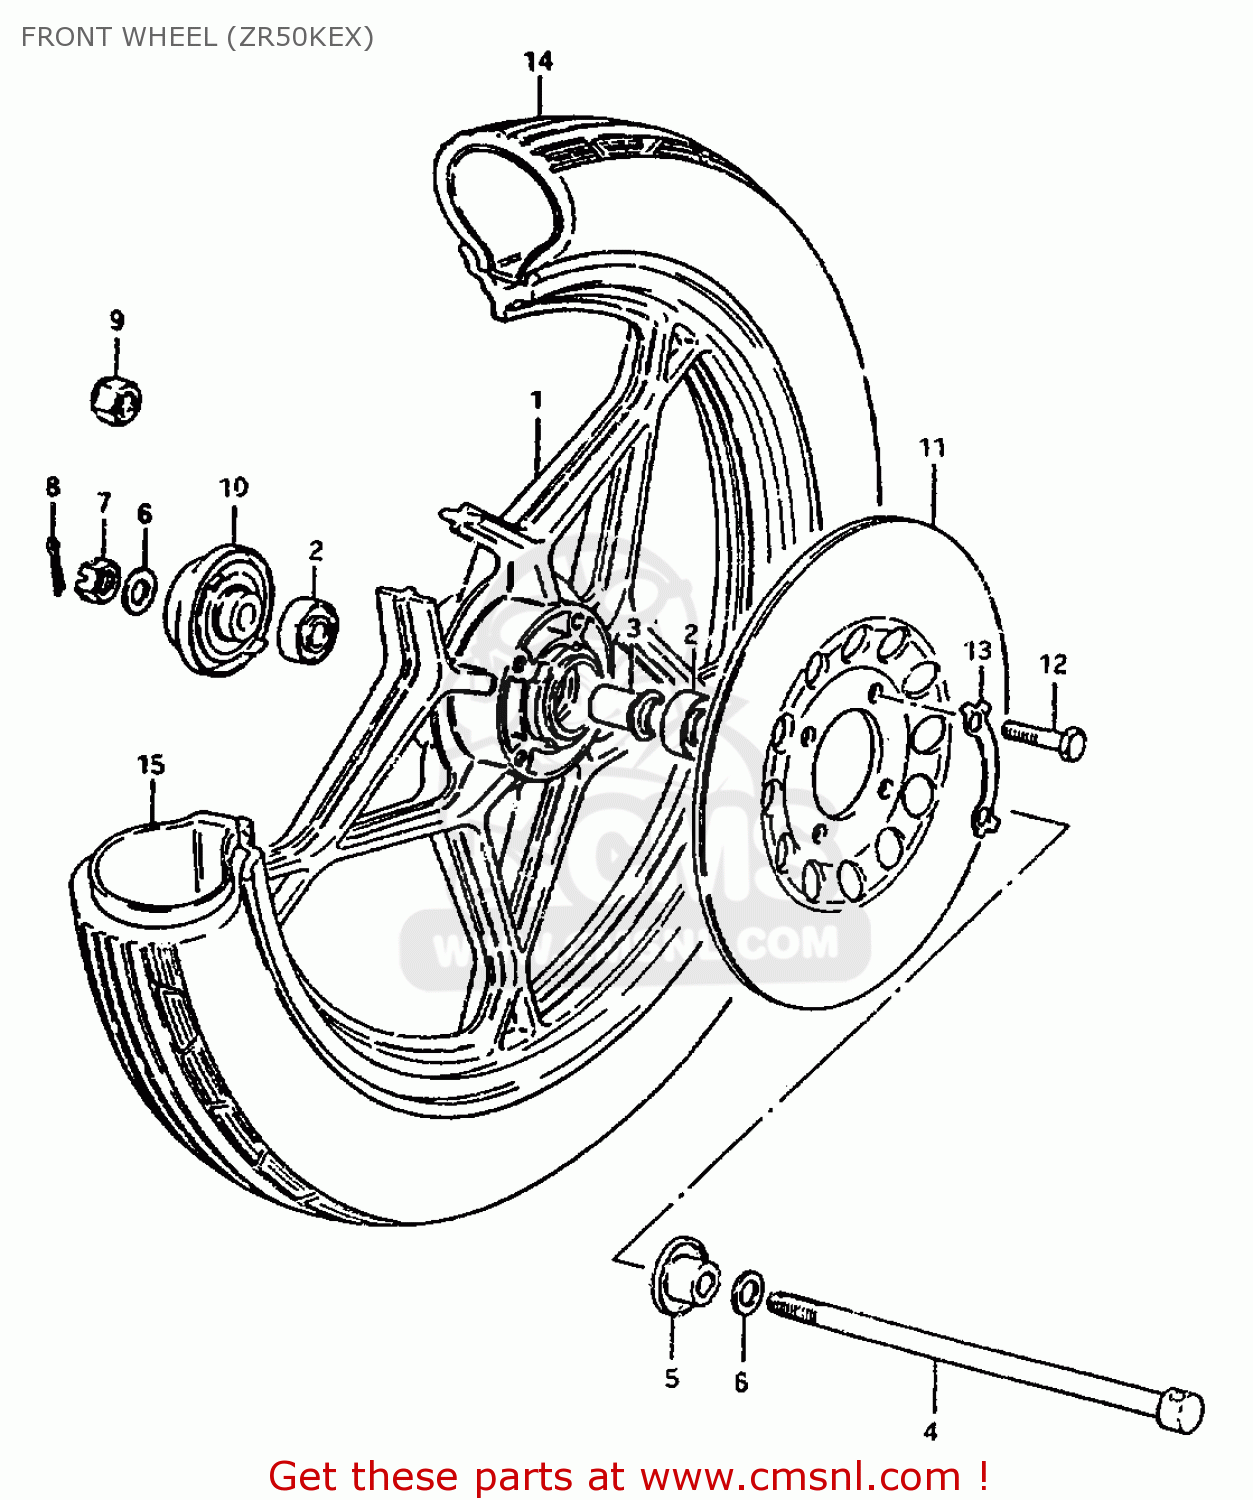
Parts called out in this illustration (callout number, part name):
1	WHEEL, FRONT (J18X1.140 DOT)
2	BEARING
3	SPACER
4	AXLE,FRONT
5	SPACER,FR AXLE,L
6	WASHER(10.5X22X2.3)
7	NUT
8	PIN 20X20
10	BOX, SPPEDOMETER GEAR
11	DISC,FR BRAKE
12	BOLT(8X30)
13	WASHER
14	TIRE,FR(2.50-18 40L NF2)
15	TUBE,INNER
